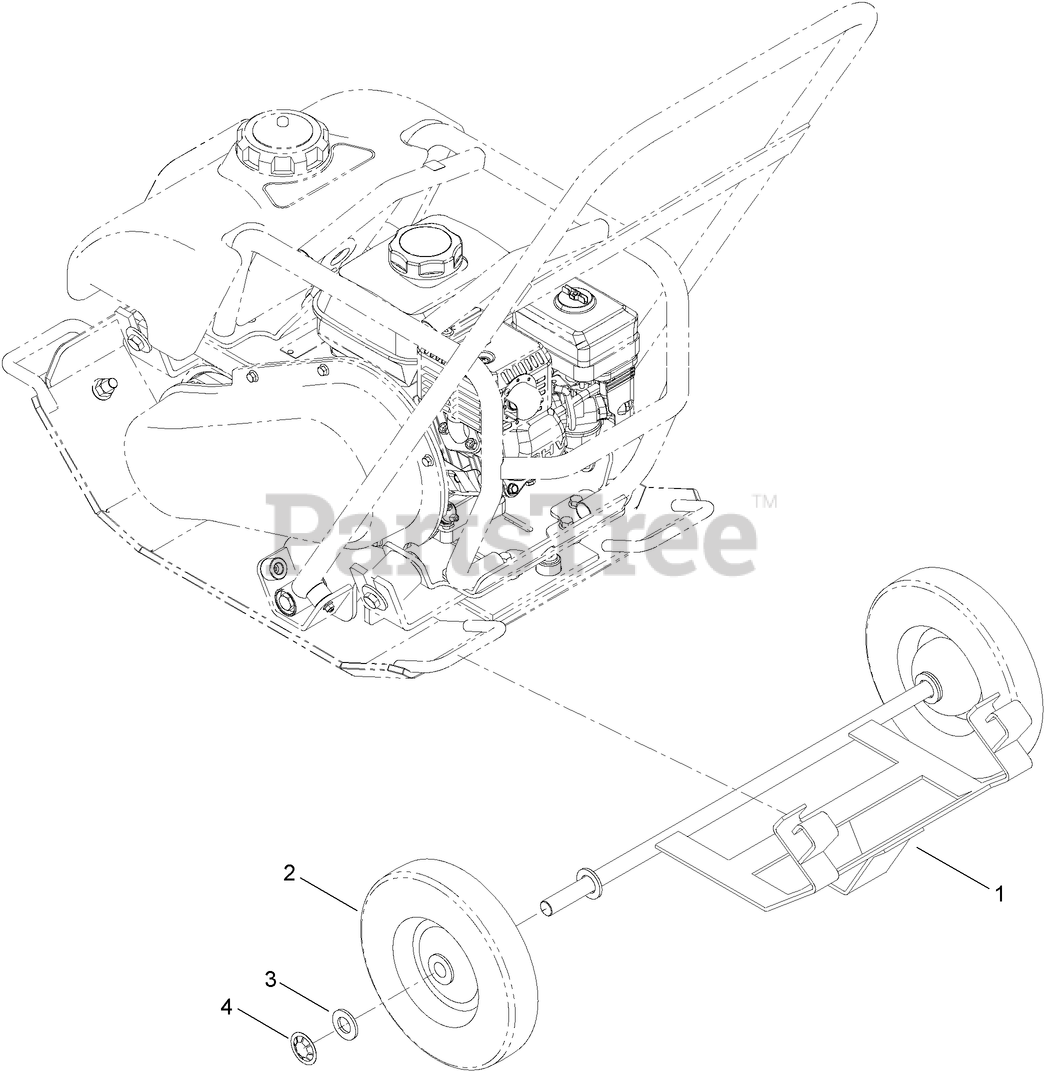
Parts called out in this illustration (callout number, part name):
1	BASE-EZ WHEEL
3	WASHER-FLAT
4	NUT-PUSH
